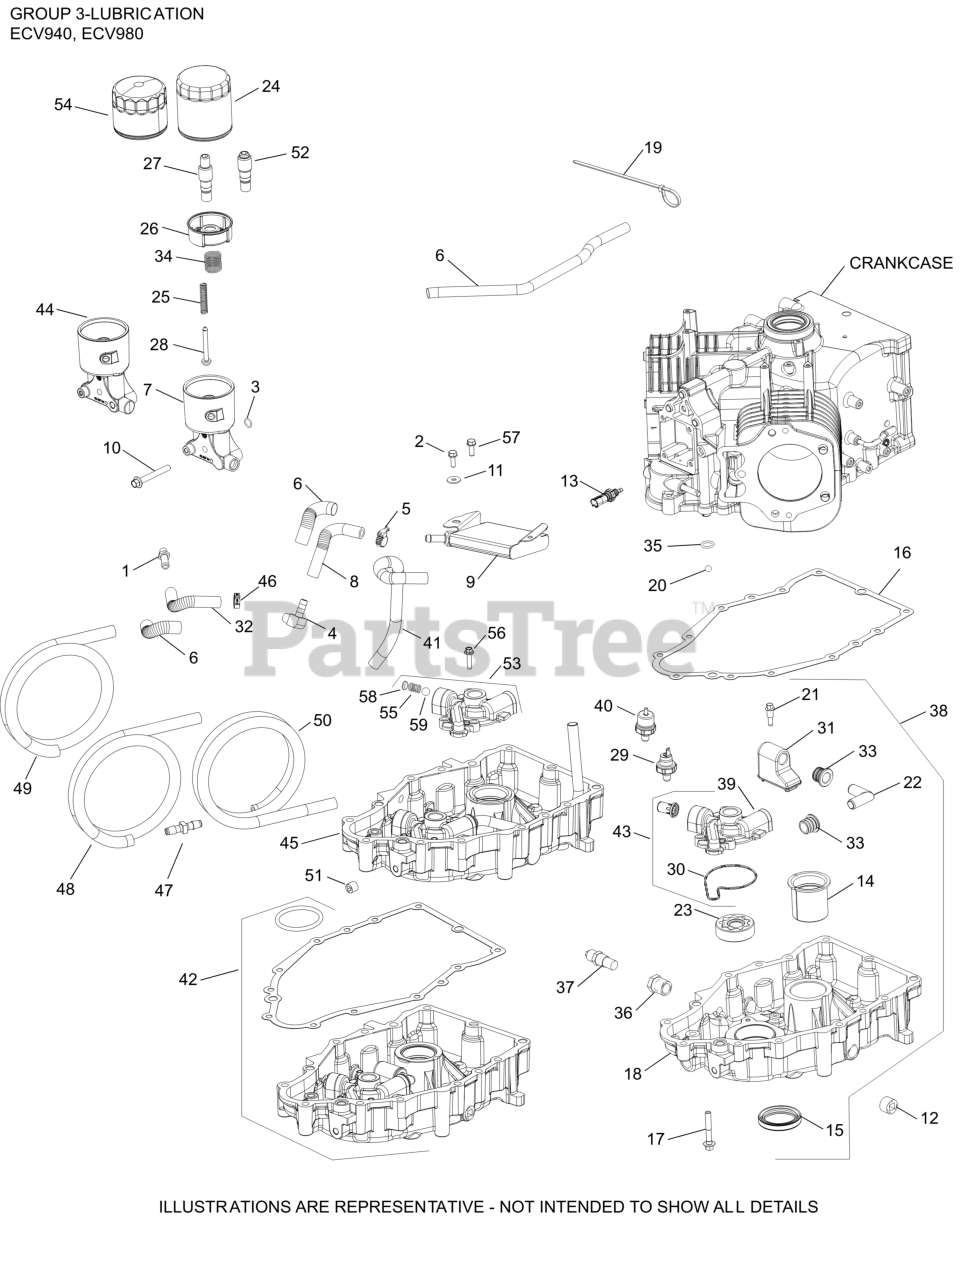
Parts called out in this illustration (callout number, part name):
1	FITTING, HOSE TO PIPE
3	O-RING, OIL PICK-UP
4	FITTING, 90 DEG. BARBED
6	SLEEVE, ANTI ABRASION-USE 25 431 12-S
7	HOUSING, VERTICAL OIL FILTER - MACHINED
8	HOSE, OIL SUPPLY
9	COOLER, OIL ASSEMBLY
10	SCREW, FLG M8X1.25X60
11	WASHER, FLAT 1/4"
12	PLUG, PIPE 1/2 NPTF SQ CTSK
13	SENSOR, TEMPERATURE
15	SEAL, OIL (LEFT-HAND HELIX, PTO)
16	GASKET, OIL PAN
17	SCREW, HEX FLANGE
19	TIE, CABLE
20	KIT, CHECK BALL
21	SCREW, SHD THD FRM M6X.0X6.5
22	TUBE, OIL PICK-UP
23	PUMP ASSEMBLY, OIL/GEROTOR
24	OIL FILTER
25	SPRING, OIL FILTER VALVE
26	CUP, OIL FILTER ASSEMBLY
28	VALVE, OIL FILTER
29	SWITCH, OIL PRESSURE
30	O-RING, OIL PUMP HOUSING
31	HOUSING, OIL PICK-UP ASSEMBLY
32	HOSE, OIL RETURN
33	SEAL, PICK-UP TUBE
34	SPRING, OIL FILTER CUP
38	KIT, OIL PAN
46	CLAMP, HOSE OETIKER
52	NIPPLE, OIL FILTER ASSEMBLY
55	SPRING, COMPRESSION
56	SCREW, HEX FLANGE M6 X 1
57	SCREW, HEX HEAD
58	PLUG, CUP
59	PRESSURE RELIEF BALL
